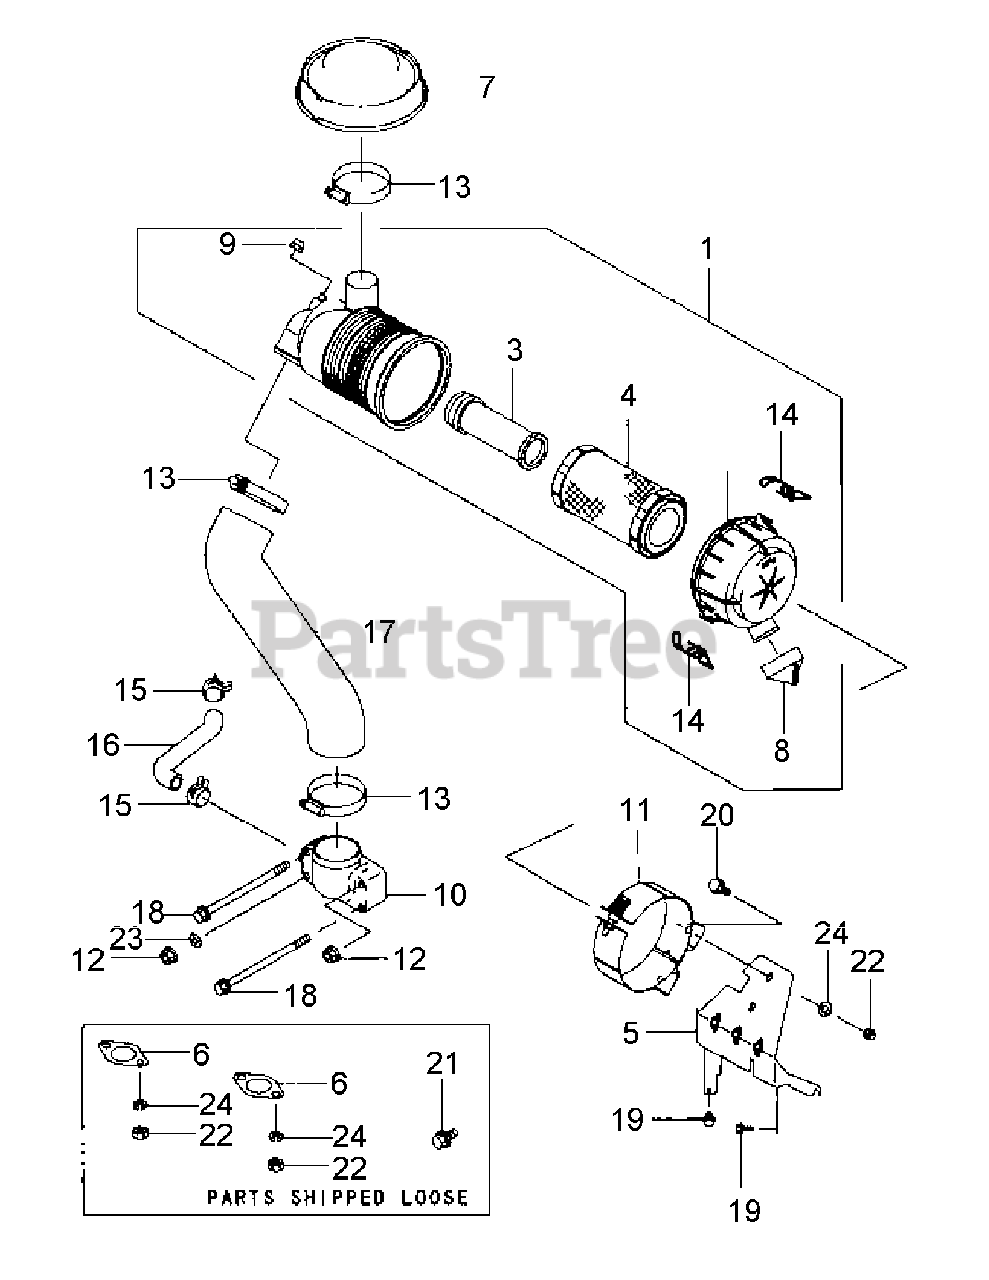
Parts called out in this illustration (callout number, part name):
1	AIR FILTER ASSY
1	AIR FILTER CAP
3	INNER FILTER ELEMENT
4	OUTER FILTER ELEMENT
6	MUFFLER GASKET
7	CAP, INTAKE
10	INTAKE PIPE
13	CLAMP
14	CLAMP, CAP
16	CLAMP
18	TUBE
20	FLANGED BOLT
21	FLANGED BOLT
22	FLANGED BOLT
23	SMALL HEX NUT
24	PLAIN WASHER
24	SPRING WASHER
